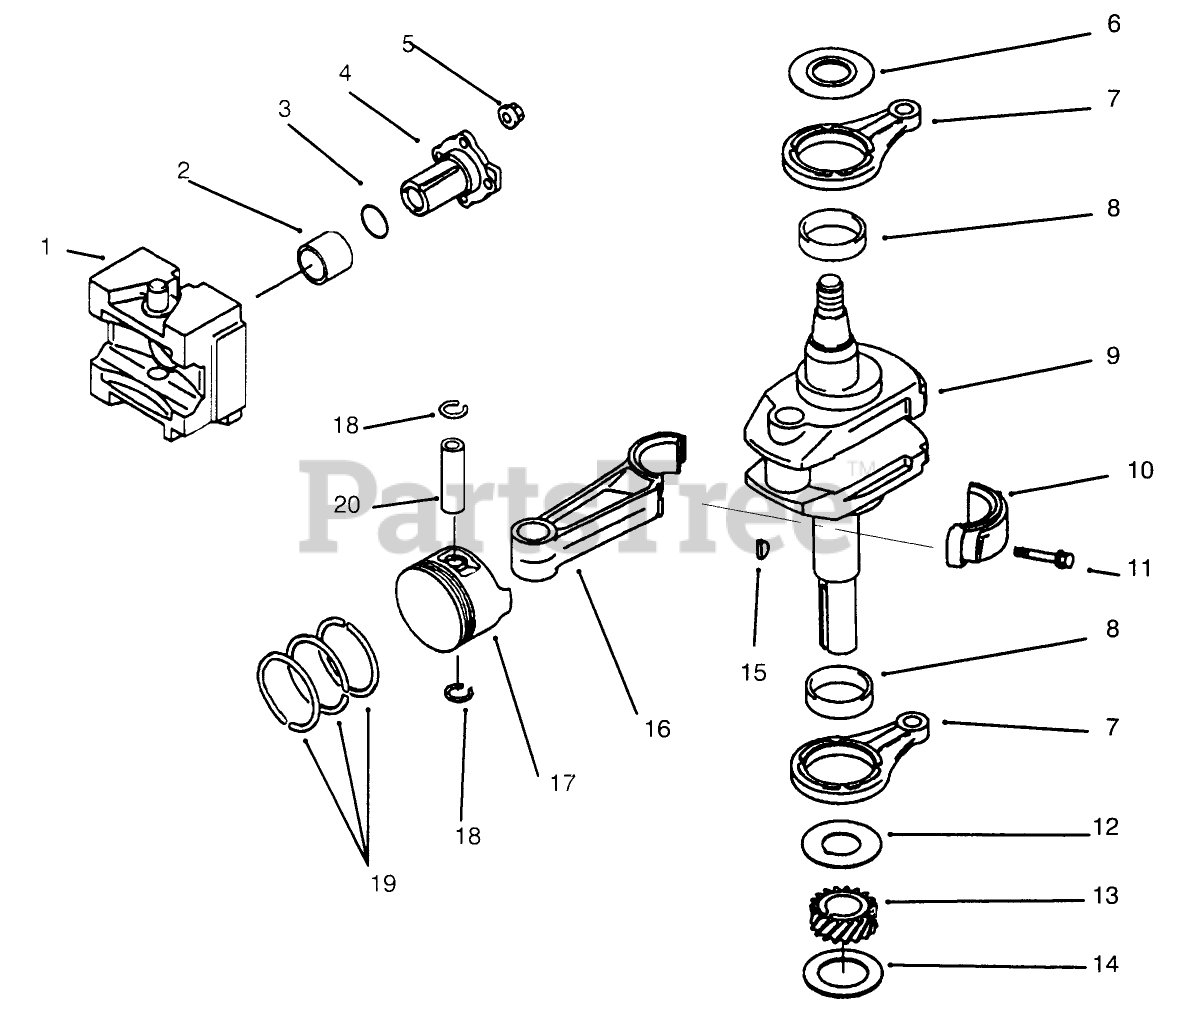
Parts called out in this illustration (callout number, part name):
1	Weight Complete (includes item 133)
2	Bushing
3	O-Ring
4	Shaft
5	Nut
6	Spacer
7	Rod Incl #8
8	Bearing
9	CrankshaftASM
10	Cap-Rod
11	Bolt
12	Spacer
13	Gear
14	Shim (1.18)
15	Key
16	Connecting Rod Ass-y-Standard (includes item 44)
17	Piston
18	Ring-Snap
19	Piston Ring Set
20	Pin-Piston
